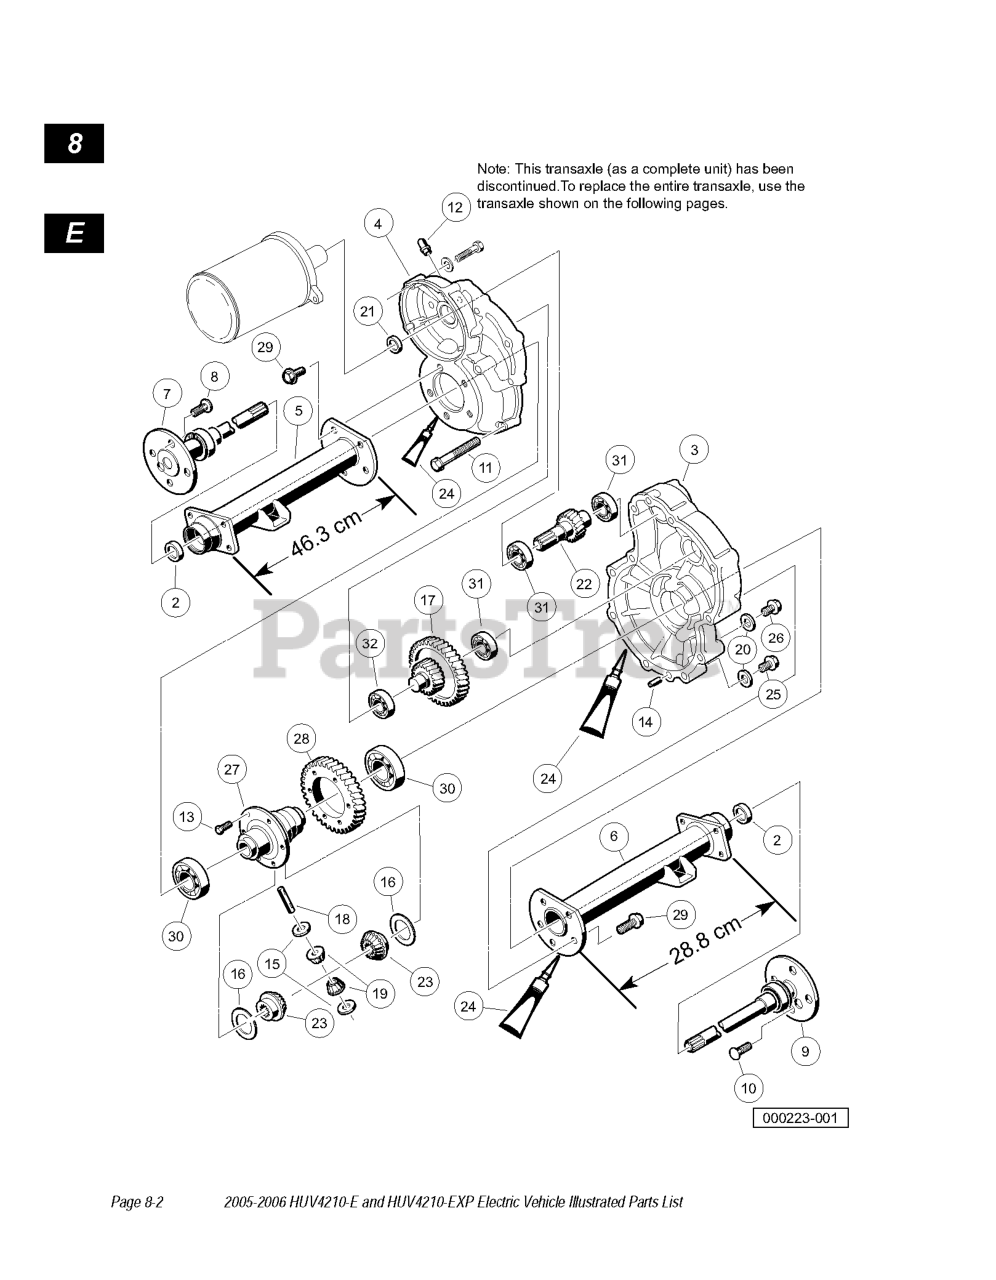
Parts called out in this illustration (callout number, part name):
2	AXLE SHAFT OIL SEAL
3	GEAR CASE LEFT HAND
4	GEAR CASE, RIGHT HAND
5	AXLE TUBE ASSY, RIGHT HAND
6	AXLE TUBE ASSY, LEFT HAND
7	AXLE ASSEMBLY RIGHT
9	AXLE ASSEMBLY, LEFT
11	SCREW, M8-1.25 X 60MM HEX HEAD
13	SCREW M10-1.25 X 25MM
14	PIN, 11MM OD X 8.5MM ID X 10MM
15	WASHER, THRUST
16	WASHER THRUST
17	INTERMEDIATE SHAFT ASSEMBLY
18	PIN, 15.99MM X 88.7MM DOWEL
19	GEAR, DIFFERENTIAL IDLER
22	SHAFT, INPUT
23	GEAR, DIFFERENTIAL
24	SEALANT
25	PLUG M14-1.5X12MM MAGNETIC
26	PLUG M14-1.5X12MM HEX
27	HOUSING DIFFERENTIAL 6 BOLT
28	GEAR DIFFERENTIAL 6 BOLT
29	SCREW FLG HD M10X1.5X30
30	INNER AXLE, TUBE BEARING
